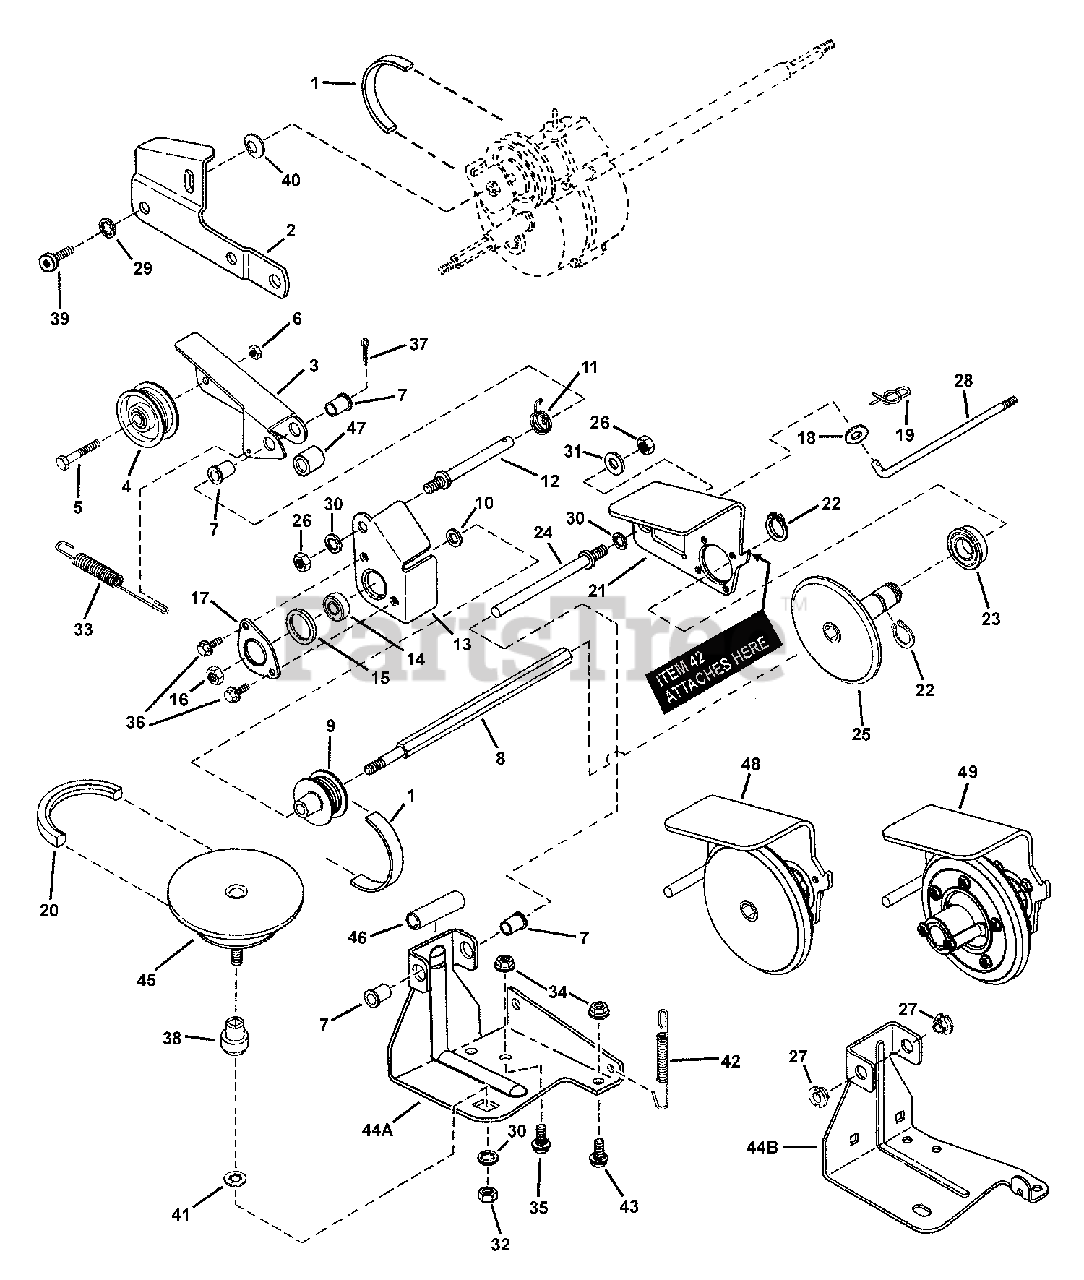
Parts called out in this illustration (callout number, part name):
1	BELT, Poly-V
2	LINK, Differential (Comm.)
3	ARM, Clutch Idler
4	PULLEY, Idler, V21
5	SCREW, 1/4-28 x 1-3/8" Hex Head Cap, GR 5
6	NUT, 1/4-28 Hex Top Lock
7	BUSHING, Flange, .381 x .625 x .62
8	SHAFT, Hex Drive
9	PULLEY, Poly-V (2" O.D.)
10	WASHER, 11/32" Flat
11	SPRING, Idler- Torsion
12	STUD, Idler (3/8-24 thread)
13	HOLDER, Bearing (Inner Half)
14	BALL BEARING, Spherical O.D., .38 I.D.
15	O-RING, V21
16	NUT, 3/8-24 Hex Center Lock, GR 5
17	HOLDER, Bearing (Outer Half)
18	WASHER, .28 x .63 x .06 Flat
19	COTTER PIN, .06 x .50 YZ
20	BELT, Engine Drive (Stretch)
21	THRUST PLATE, Short
22	RETAINING RING, .625 External
23	BALL BEARING, 3/4" Bore
24	GUIDE, Thrust Plate (3/8-24 thread)
25	DISC, Driven (Cantilever)
26	NUT, 3/8-24 Hex
27	BUSHING, Nylon (.390 ID, .490 OD)
28	LINK, Transfer (1/4-28 thread)
29	WASHER, 5/16" Internal Tooth Lock
30	WASHER, 3/8" Internal Tooth Lock
31	WASHER, 3/8" Flat
32	NUT, 3/8-16 Hex
33	SPRING, Clutch - 21S
34	NUT, 5/16-18 Hex Flange Lock, GR 5
35	BOLT, 5/16-18 x 1/2", Short Neck Carriage, GR 5
36	SCREW, 1/4-20 x 1/2" Hex Flange Self-Tap
37	COTTER PIN, 3/32 x 1/2"
38	BUSHING, Powdered Metal
39	SCREW, 5/16-18 x 1/2" Pan Head Self-Tap (Torx)
40	WASHER, 44 x .78 x .025 Curved
41	RETAINER, 3/8" Bolt
42	SPRING, Wheel Drive
43	BOLT, 5/16-18 x 5/8" Short Neck Carriage GR 5
44A	BRACKET, Deck
44A	BRACKET ASSEMBLY, Deck (Includes 7, 44A & 46)
44B	BRACKET ASSEMBLY, Deck (Includes 44B & 7012117 bushing)
45	DRIVE DISC, Steel
45	* KIT, Drive Disc Assembly
46	SPACER, (.500 ID x .65 OD x 1.75 Long)
47	SPACER, Idler Arm (.500 ID x .970 Long)
48	ASSEMBLY, Driven Disc (includes items 21-26, 30&31)
49	ASSEMBLY, Driven Disc - Commercial (Can be used instead of items 21-26, 30&31)
